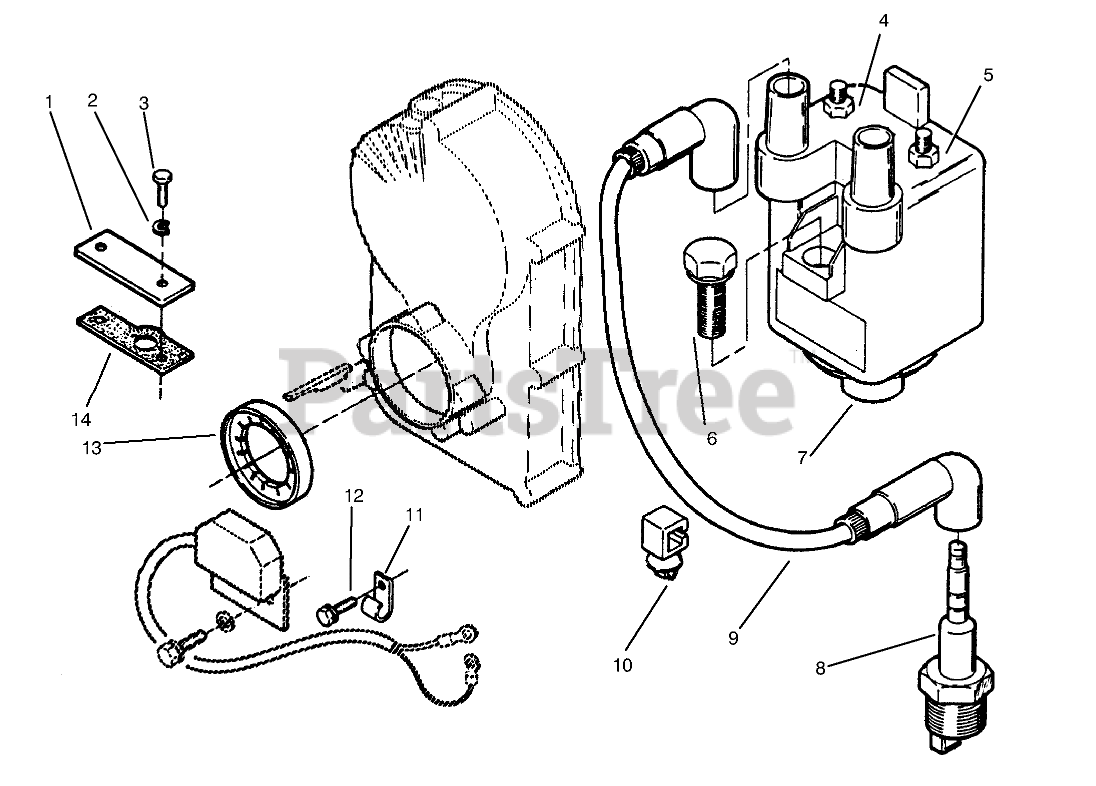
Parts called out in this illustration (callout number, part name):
1	PLATE-COVER
2	WASHER-FLAT
3	SCREW - CAP HEX HEAD
4	NUT-HEX FLANGE
5	NUT-HEX FLANGE
6	SCREW-HH
7	COIL-BATTERY IGNITION
8	SPARK PLUG
9	Wire-Plug
10	WIRE ROUTING CLIP
11	CLIP-WIRE
12	HEX-HEAD CAP SCREW
13	ROTOR-IGNITION
14	Gasket-Plate
